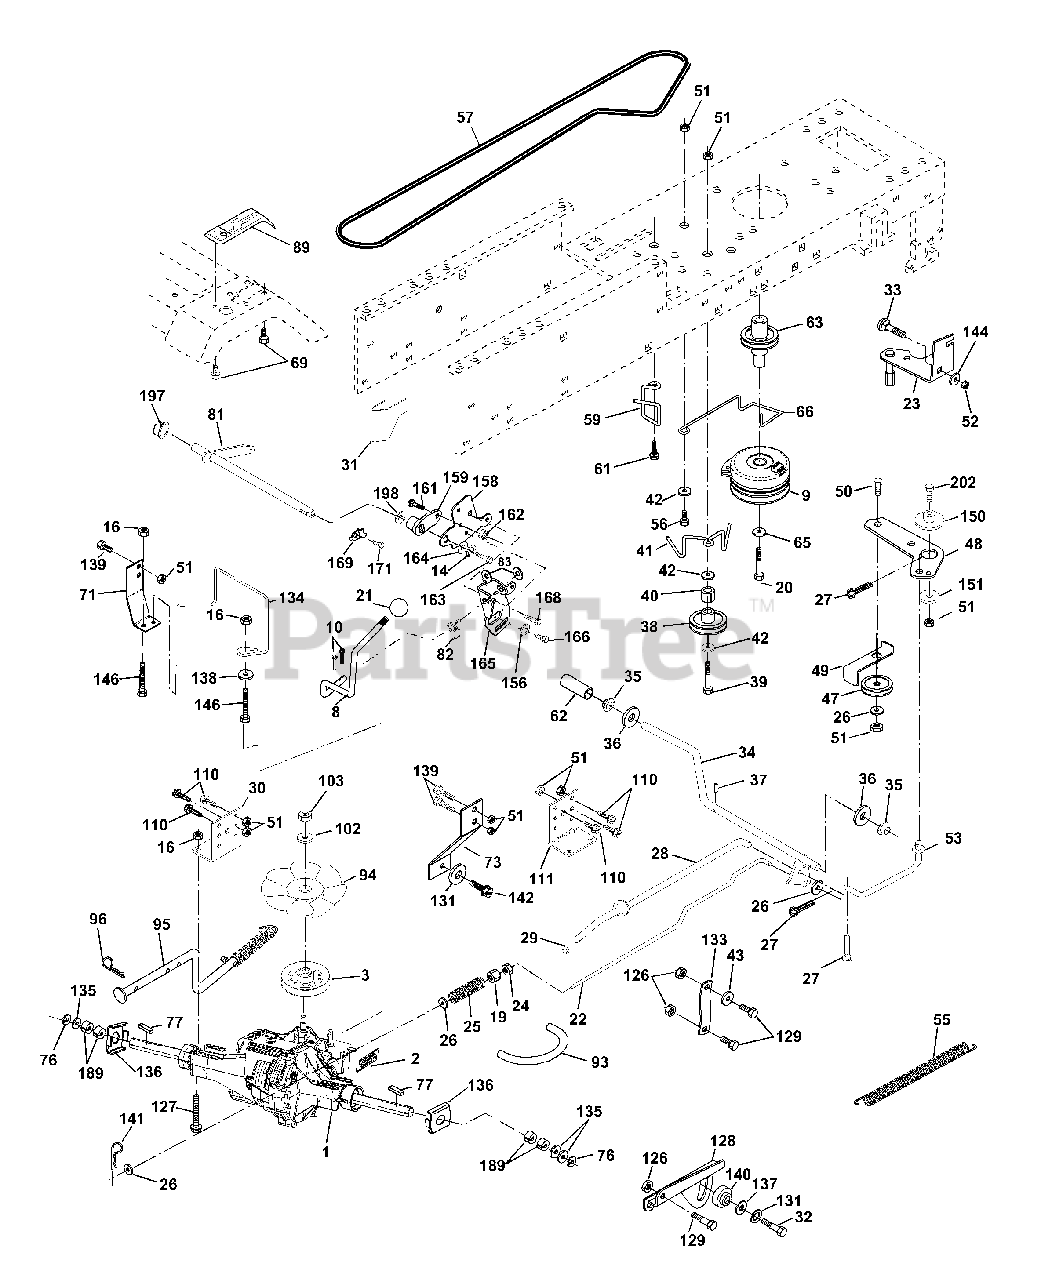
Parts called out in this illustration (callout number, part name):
2	Spring, Brake Return
3	Pulley, Transaxle
8	Rod Shift Fender Adjust
9	Clutch Elect EVX 80 lb.
10	Pin, Cotter 1/8 x 1
14	Washer Lock Hvy Helical
16	Nut, Lock Hex w/Ins. 5/16-18 UNC
19	Nut, Lock Hex w/Ins. 3/8-16 Unc
20	Bolt Hex 7/16-20 x 4-1/4 Ga. 5
21	Knob Delux 1/2-13 Unc
22	Rod, Brake
23	Bracket Asm Anti Rot Evx 2000
24	Nut, Hex Jam 3/8-16
25	Spring, Rod, Brake
26	Washer 13/32 x 13/16 x 16 Ga.
27	Pin Cotter 1/8 x 3/4 Cad SD
28	Rod, Brake, Park
29	Cap, Brake Parking Black
30	Bracket, Transaxle
31	Keeper, Belt, Transaxle
32	Hex Bolt 5/16-18 UNC x 3/4
33	Bolt Rdhd Sqnk 5/16-18 Unc x 3/4
34	Shaft, Foot Pedal
35	Bearing Nylon
37	Pin, Roll
38	Idler, Flat
40	Spacer, Split
41	Keeper, Idler
42	Washer 13/32 x 13/16 x 12 Ga.
43	Washer 11/32 x 5/8 x 12 Ga.
47	Pulley, Idler
48	Bellcrank Clutch Grnd Drv Stl
49	Retainer, Belt
50	Bolt Hex Hd 3/8-16 Unc x 1-1/2
51	Nut, Crownlock 3/8-16
52	Nut Crown Lock 5/16-18 Blk D
53	Link, Clutch
55	Spring, Return, Clutch
56	Bolt, Hex 3/8-16 UNC x 1-1/4
57	V-Belt Drive
59	Keeper Belt Centerspan
61	Screw 3/8-16 x 3/4
62	Cover, Foot Pedal
63	Engine Pulley
65	Washer
66	Keeper, Belt Engine
71	Torque Fastener L.H.
73	Torque Fastener R.H.
77	Key, Square
81	Shaft Asm Cross Tapered
82	Spring, Torsion
83	Washer 17/32 x 3/4 x 16 Ga.
89	Console, Shift
95	Control Assembly Bypass Hydro
96	Retainer, Spring 1"
102	Washer .501 x 1.50D
103	Nut Hex Jam Toplock 1/2-20 UNF
110	Bolt, Hex 3/8-16 UNC x 3/4
127	Bolt, Hex 5/16-18 UNC x 3
129	Bolt 5/16-18 UNC
131	Washer Lock 5/16 NDM PLTD
133	Link Transaxle Hydro 3000
134	Belt, Guide
135	Washer 1-1/32 x 1-5/8 x 16 Ga.
137	Washer 11/32 x 3/4 x 12 Ga.
138	Washer 11/32 x 1.25 x 16 Ga.
139	Bolt, Hex 3/8-16 UNC x 3/4
142	Bolt 5/16 x 24 x 1
144	Washer 11/32 x 5/8 x 16 Ga SD
146	Bolt Hex Flghd 5/16-18 x 2-1/4
150	Bushing Bellcrank Grd Drive
151	Washer 13/32 x 2 x 10 Ga.
156	Washer Srrted 5/16ID x 1.125
158	Bracket Shift Mount
159	Hub Tapered Flange Shift Lt
161	Bolt Rdhd Sqnk 1/4-20 x 3/4 Gr 5
162	Nut Crownlock 1/4-20 Unc
163	Bolt Hex Fin 1/4-20 Unc x 1 Gr 5
164	Washer 5/8 x .281 x 10 Ga
165	Bracket Pivot Lever
166	Screw 5/16-18 x 5/8
168	Bolt Shoulder 5/16-18 x .561
169	Plate Fastening Lt
171	Screw Thdrol 3/8-16 x 1/2
189	Washer Spacer Axle
197	Nyliner Snap-in 5/8" ID
198	Washer Nyl 7/8ID x 105" Hyd CRD
202	Bolt Carr Sh 3/8-16 X 1-1/2 Gr 5
